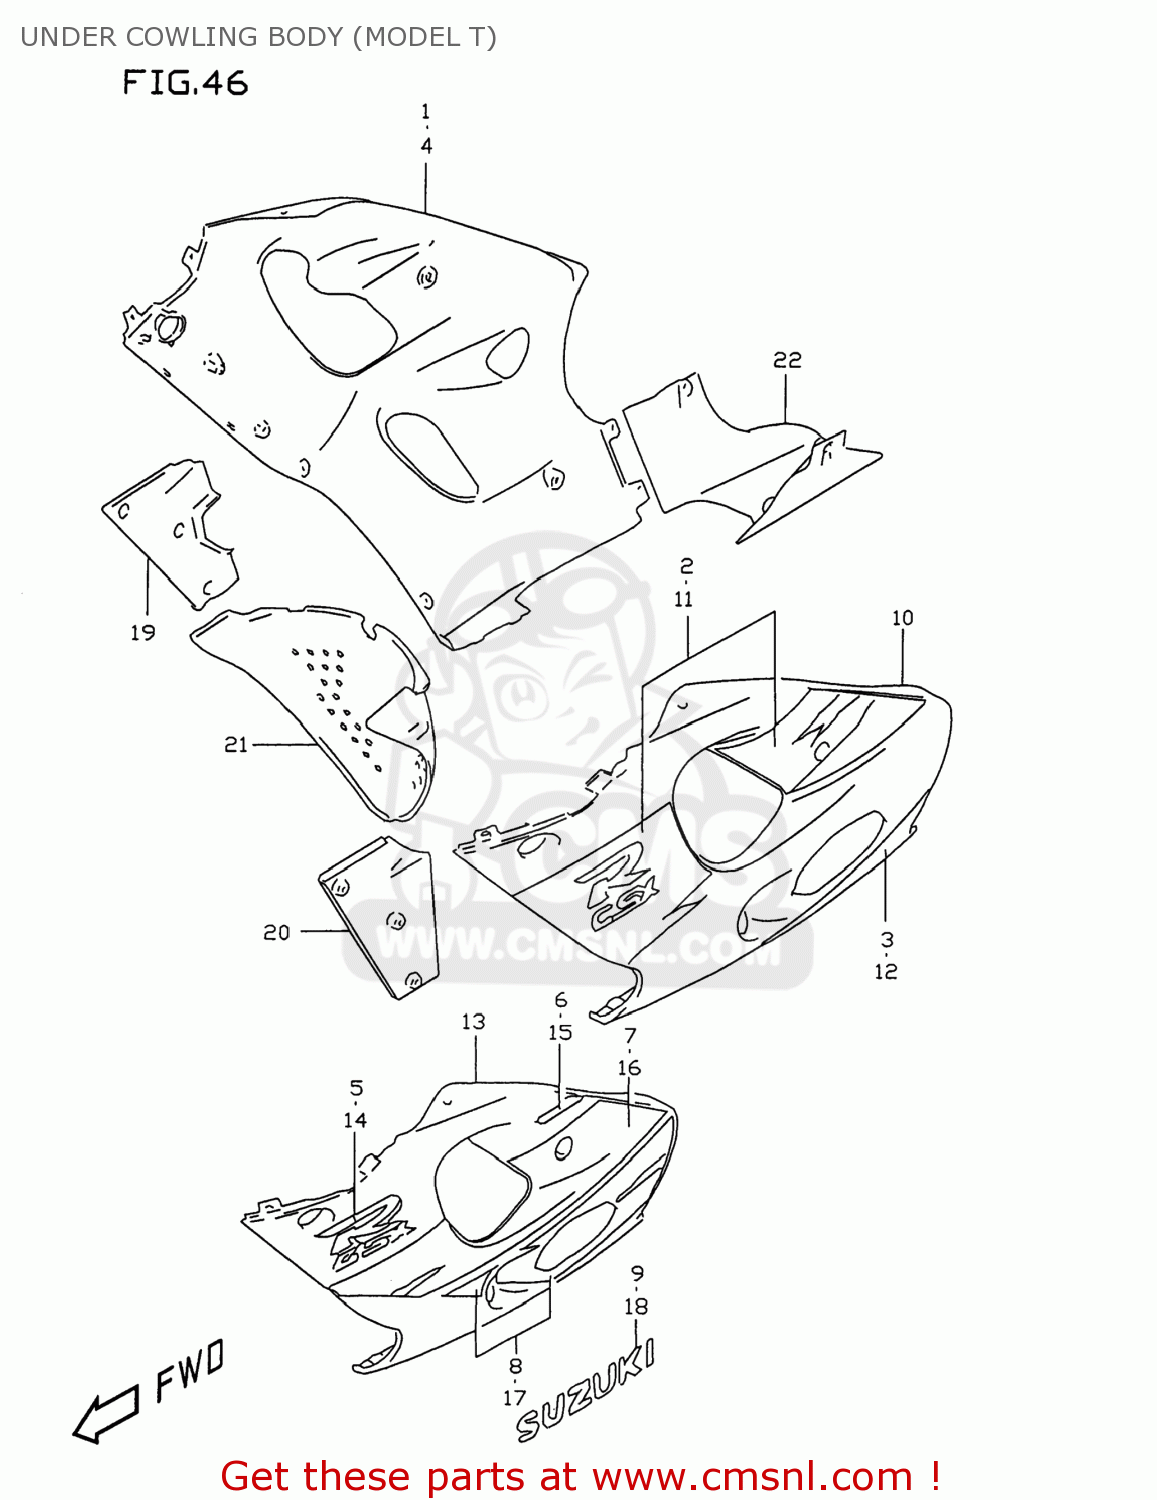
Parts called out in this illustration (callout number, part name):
1	COWLING ASSEMBLY,UNDER,RIGHT (
2	TAPE SET,COWL UNDER,R
3	TAPE,COWL UNDER,R
4	COWLING ASSEMBLY,UNDER,RIGHT
5	EMBLEM,COWLING UNDER
6	TAPE,COWL UNDER UPR,R
7	TAPE,COWL UNDER CTR,R
8	TAPE SET,COWL UNDER LWR,R
9	EMBLEM,SUZUKI(BLUE)
10	COWLING ASSEMBLY,UNDER,LEFT (
11	TAPE SET,COWLING,UNDER
12	TAPE,COWL UNDER,L
13	COWLING ASSEMBLY,UNDER,LEFT
14	EMBLEM,COWLING UNDER
15	TAPE,COWL UNDER UPR,L
16	TAPE,COWL UNDER CTR,L
17	TAPE SET,COWL UNDER LWR,L
18	EMBLEM,SUZUKI(BLUE)
19	COWLING,UNDER INNER,R
20	COWLING,UNDER,INNER,LEFT
21	COWLING,UNDER,CENTER
22	COWLING ASSEMBLY,UNDER,REAR
